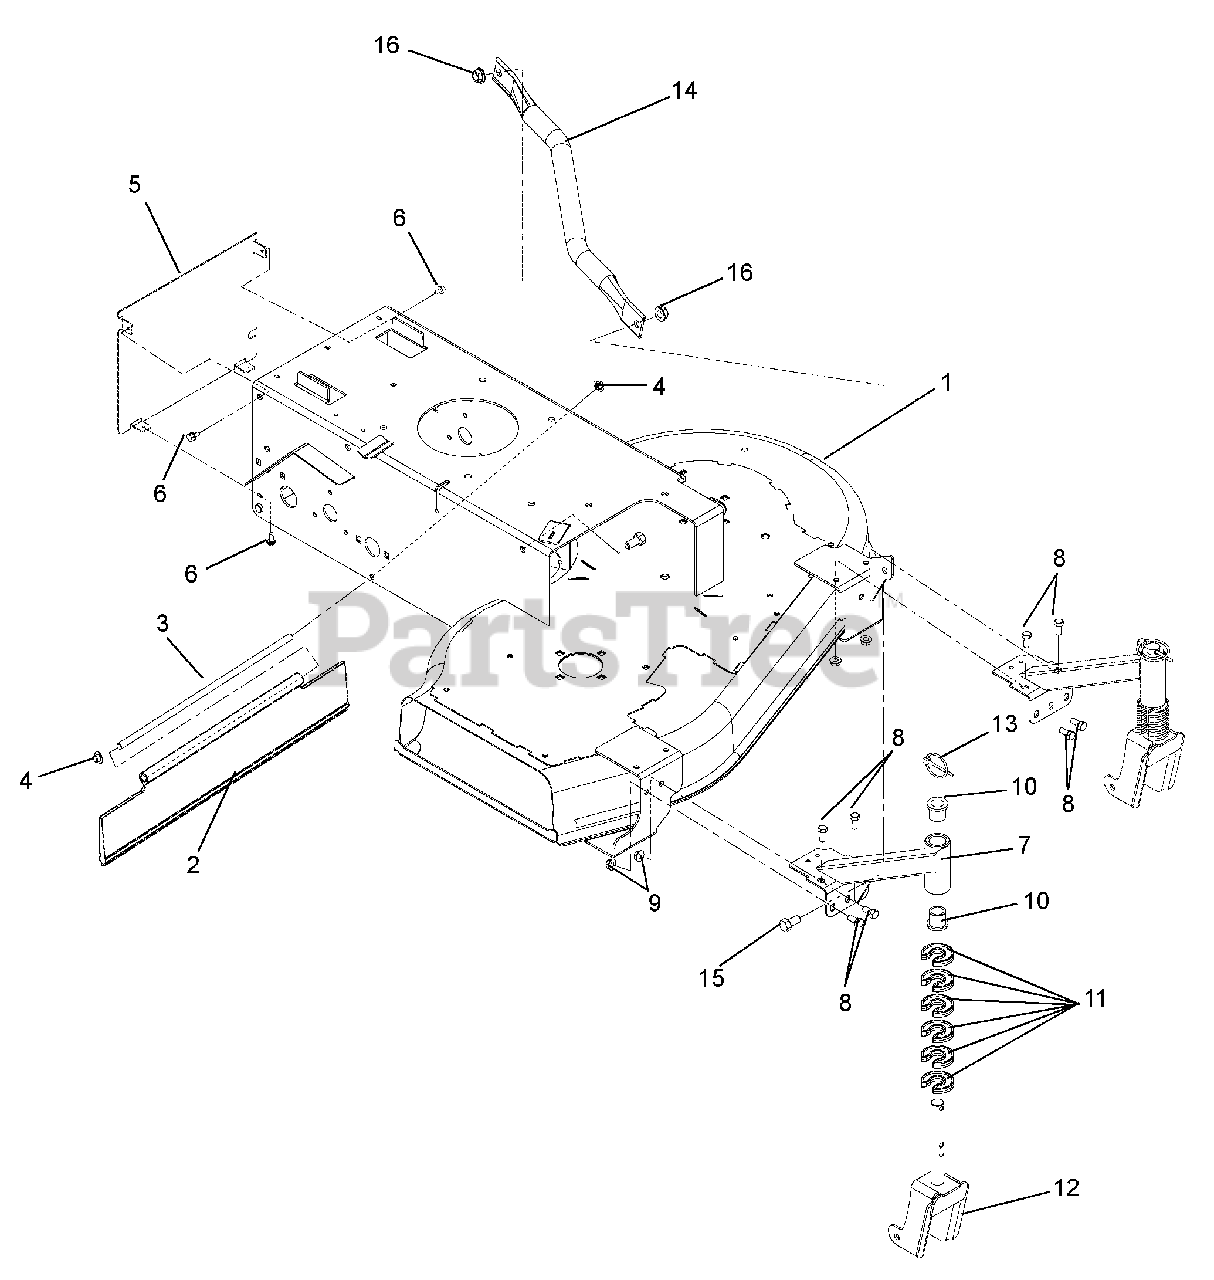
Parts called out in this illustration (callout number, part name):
1	Chassis, Wide Area Walk
2	Guard, Rear Swivel
3	Rod, Trailing Shield
4	Nut, Push .312 Dia. PAL
5	Cover, Rear Chassis
6	Screw, Tapping 10-24 x .375 Pre-Coat 80
7	Weldment, Caster Arm
8	Bolt, Hex .31-18 x .75
9	Nut, Locking Top Flange .31-18
10	Bushing 1.00 x .75 x 1.00
11	Clip, HOC Fixed
12	Fork, WAW Caster
13	Pin, Lynch .25 x 1.25
14	Strap, Frame Reinforcing
15	Bolt, Hex .38-16 x .75
16	Nut, Locking Top Flange .38-16
